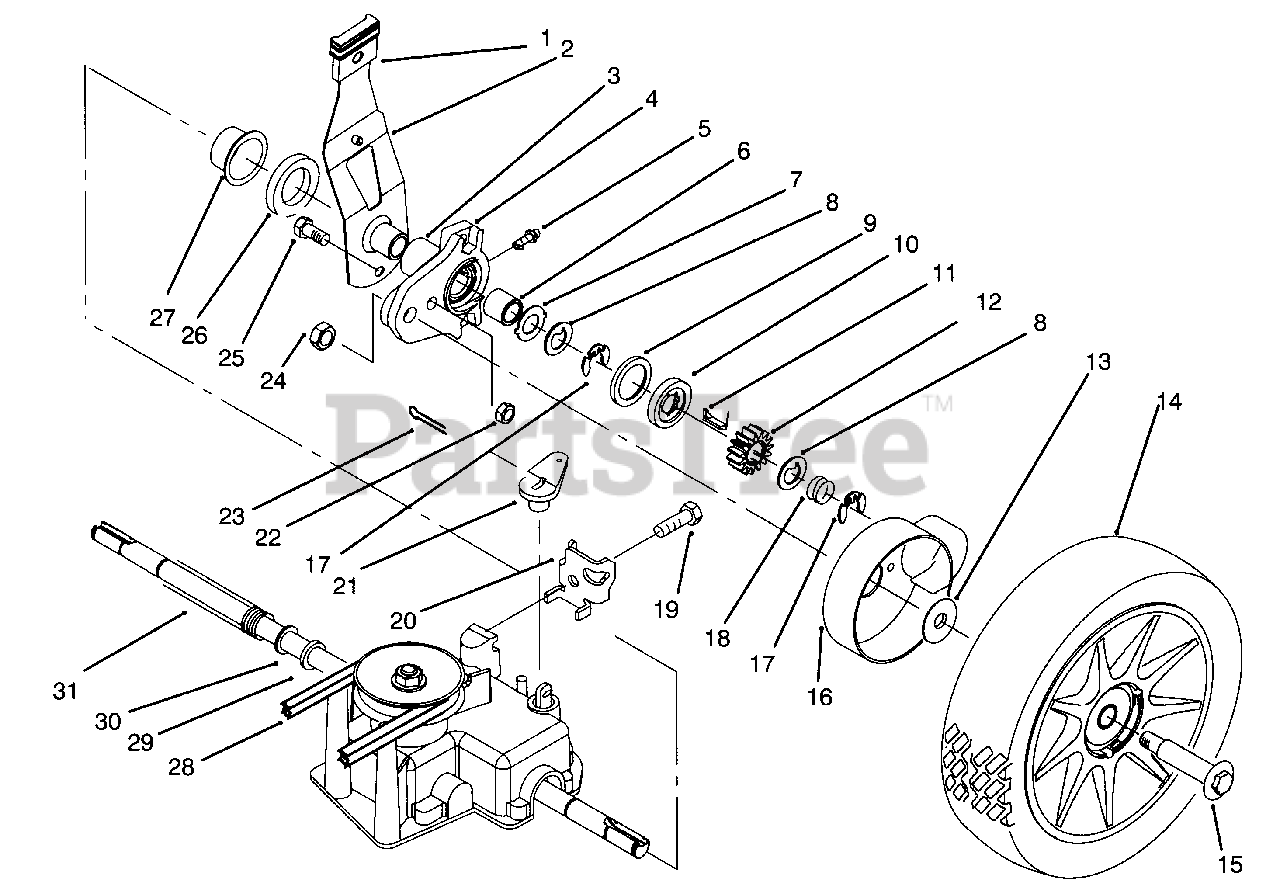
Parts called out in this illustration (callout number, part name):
1	Knob-Spring Arm
2	Arm Assembly
4	Pivot Arm Assembly
5	Fitting-Grease
7	Washer-Thrust
8	Washer-Thrust
9	Ring-Friction
10	Washer-Clutch
11	Key-Rocking, L.H.
12	Gear-Pinion
13	Washer-Stepped
14	Wheel-8"
15	Bolt-Wheel
16	Cover-Wheel
17	Ring-Retaining
18	Spring-Compression
19	Screw-Hex. Hd.
20	Retainer-Cable
21	Lever-Shift
23	Pin-Cotter
26	Spacer-Axle
27	Ring-Isolation
28	"V" Belt
29	Washer-Felt
30	Washer-Flat
31	Cover-Drive Shaft
